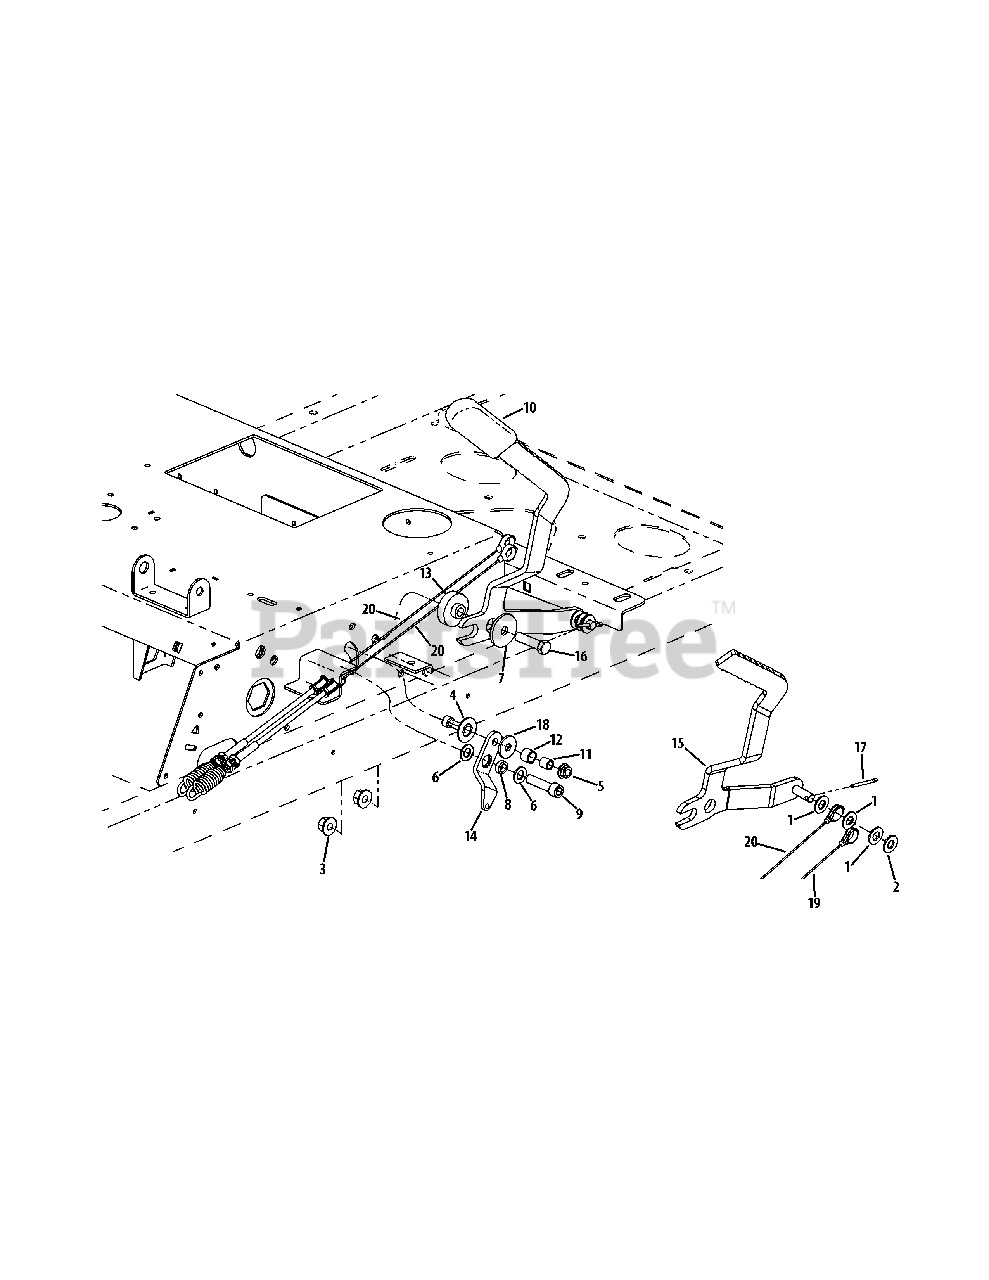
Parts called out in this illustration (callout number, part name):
1	Flat Washer, .406 x .812 x .062
2	Flat Washer, 3/8
3	Hex Nut, 3/8-16 Flange Lock
4	Slide Washer
5	Flange Lock Nut, 5/16-18
6	Washer, .375 x .738 x .063
7	Flat Washer, .390 x 1.5 x .134
8	Spacer, .380 x .563 x .196
9	Sockethead Capscrew, 3/8-16 x 1.50
10	Parking Brake Grip
11	Spacer, .322 x .438 x .44
12	Spacer, .442 x .563 x .405
13	Step Hub, .379 x 1.5 x .257/.400
14	Lockout Lever Plate
15	Brake Handle
16	Hex Head Cap Screw, 3/8-16 x 1.50
17	Cotter Pin, 1/8 x .75
18	Washer, .345 x 1.00 x .100
19	Left Hand Brake Cable
20	Right Hand Brake Cable
